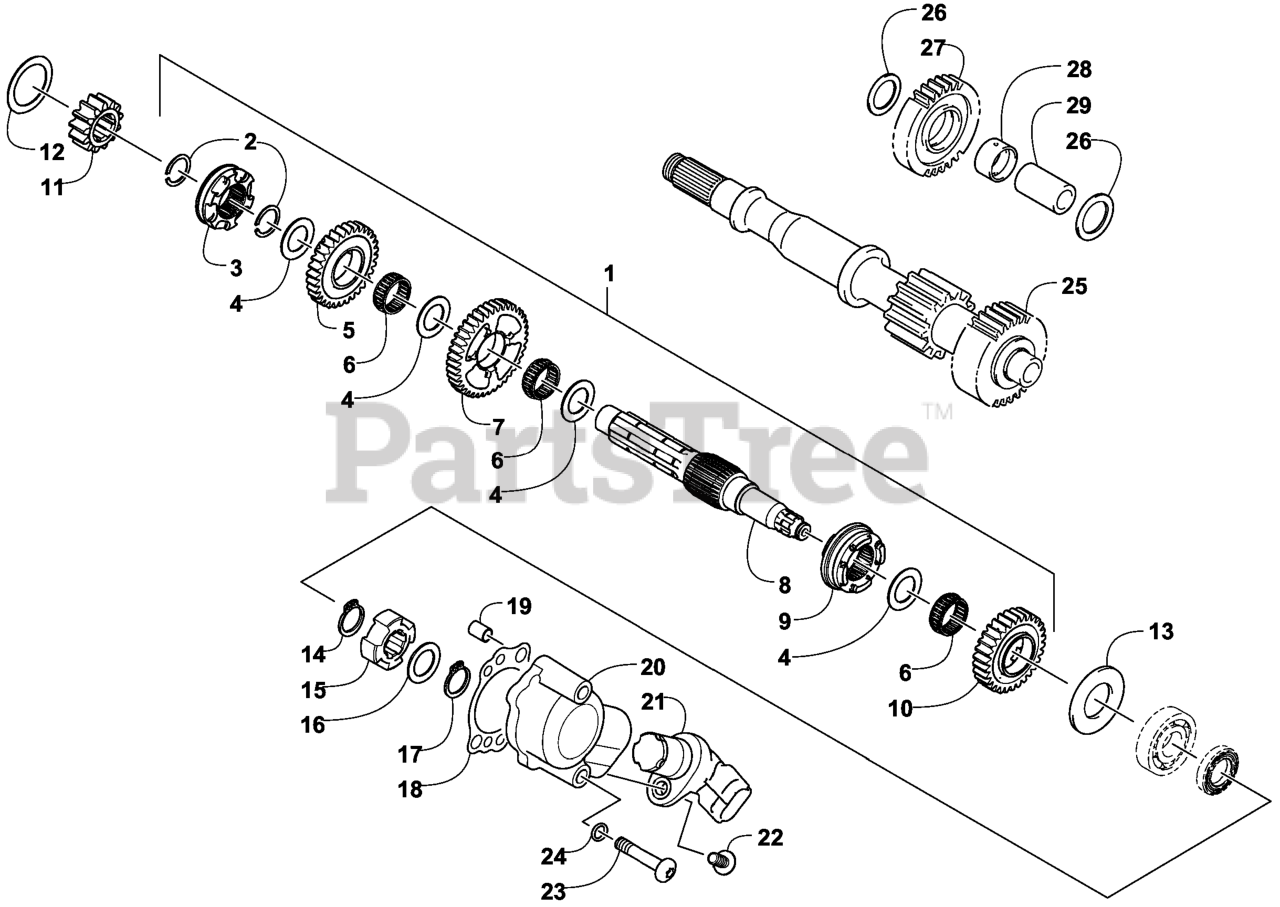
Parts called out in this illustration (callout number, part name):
1	COUNTERSHAFT ASM
2	CIRLCLIP-SHAFT, EXTERNAL
3	DOG-SLIDING, REVERSE
4	SHIM-SPACER, DRIVE GEAR
5	GEAR-DRIVEN, REVERSE (32T
6	BEARING-NEEDLE, ROLLER
7	GEAR-DRIVEN, LOW (40T)
8	COUNTERSHAFT
9	DOG-SLIDING, FORWARD
10	GEAR-DRIVEN, HIGH (30T)
11	GEAR-SPUR, 13T-13T
12	WASHER-THRUST
13	WASHER-STEEL
14	RING-RETAINING, EXTERNAL
15	TRIGGER-SENSOR, SPEEDO
16	WASHER-THRUST
17	RING-RETAINING, EXTERNAL
18	GASKET-ODOMETER DRIVE
19	PIN-SOLID DOWEL
20	HOUSING-SPEEDO SENSOR
21	SENSOR-SPEEDOMETER
24	SEAL-FASTENER
25	DRIVESHAFT
26	WASHER-THRUST
27	GEAR-REVERSE IDLE
28	BUSHING-GEAR, REVERSE IDL
29	SHAFT-REVERSE IDLE
